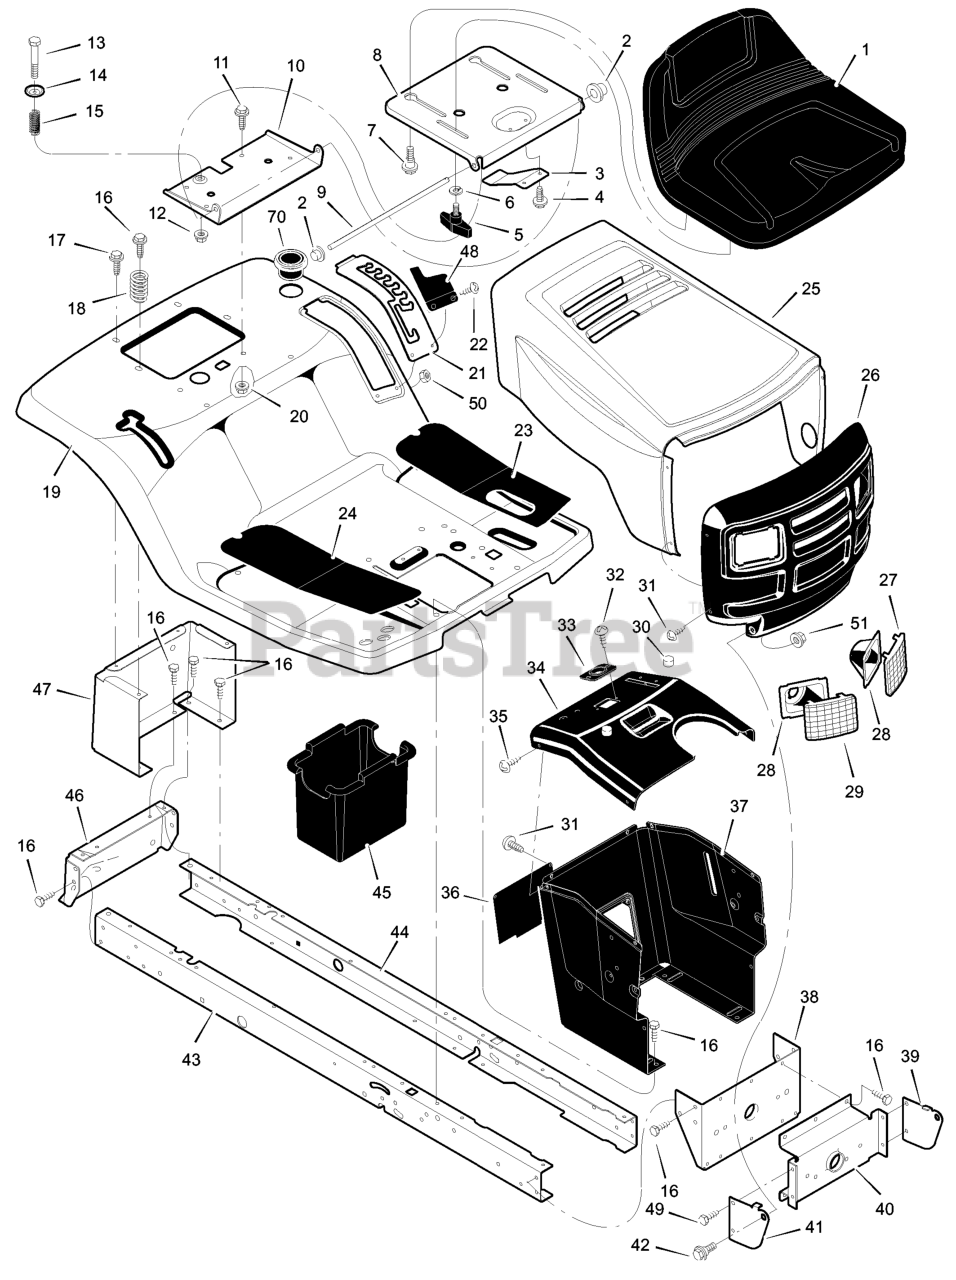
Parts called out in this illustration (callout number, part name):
1	Seat
2	Cap, Push On
5	Bolt, Wing
6	Washer
7	Bolt, Shoulder
8	Support, Seat
9	Rod, Pivot
10	Bracket, Pivot
11	Bolt
13	Bolt, Shoulder
15	Spring
19	Deck, Seat
20	Nut
21	Plate, Index
23	Mat, Left
24	Mat, Right
27	Lens, Left
29	Lens, Right
30	Bumper
31	Screw
33	Bearing, Steering
36	Panel, Access
37	Support, Dash
38	Bracket, Rear Hanger
39	Support, Left Grille
40	Axle, Hanger
41	Support, Right Grille
42	Bolt, Shoulder
43	Frame, Right
44	Frame, Left
45	Container, Battery
46	Plate, Hitch
47	Panel, Rear
48	Cover, Detent
70	Holder, Cup
